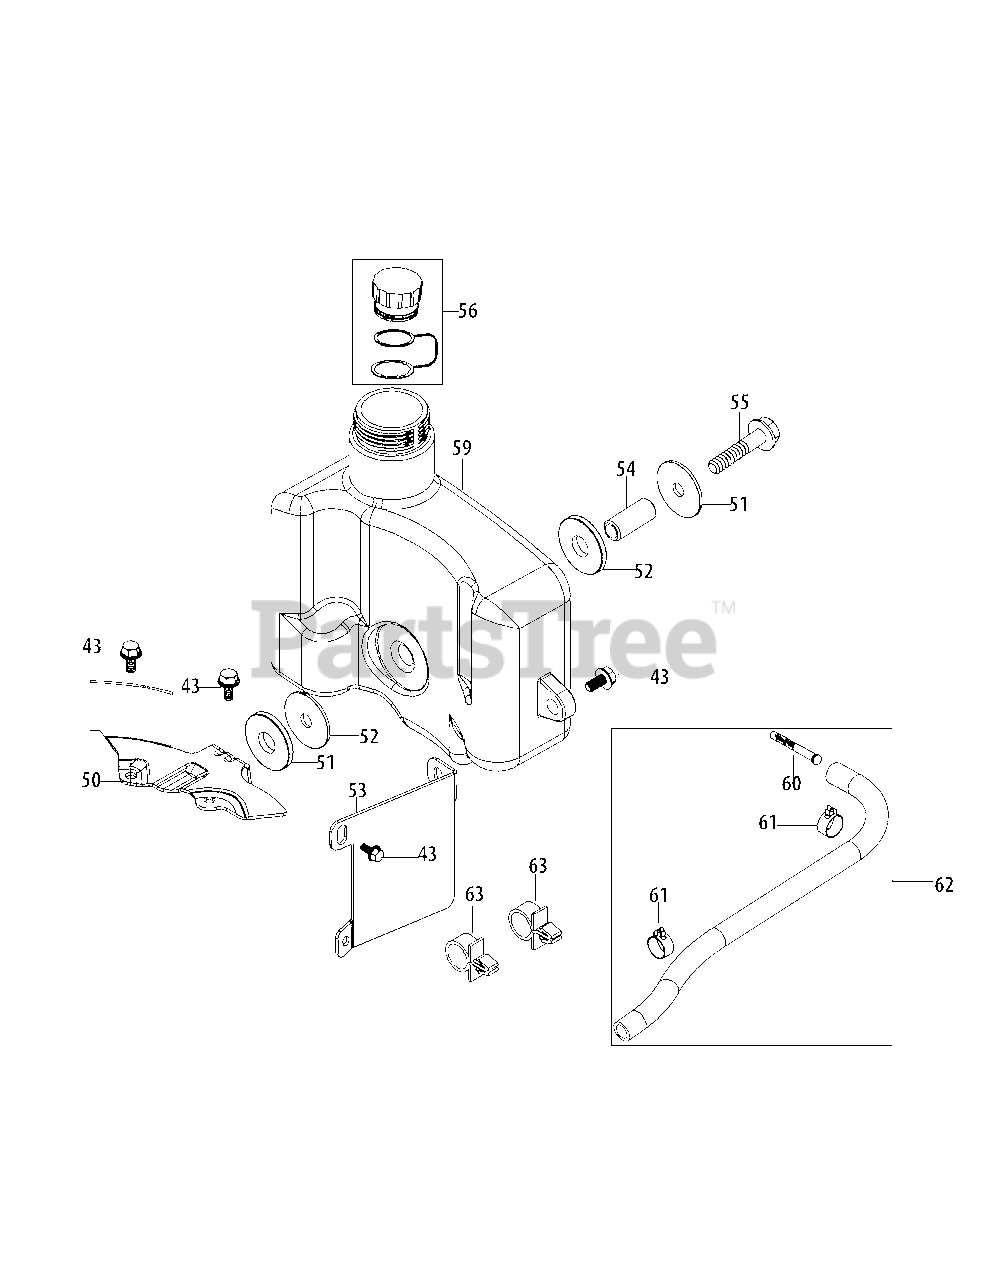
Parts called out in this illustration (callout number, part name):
43	Bolt M6X14 Multi-Purpose
50	Fuel Tank Bottom Bracket
51	Fuel Tank Washer
52	Rubber Bushing
53	Fuel Tank / Label Bracket
54	Fuel Tank Bushing
55	Bolt M8X50 Fuel Tank
56	Fuel Cap Assembly
59	Fuel Tank Assembly
60	Fuel Filter
61	Fuel Hose Clamp
63	Plastic Support Clamp
